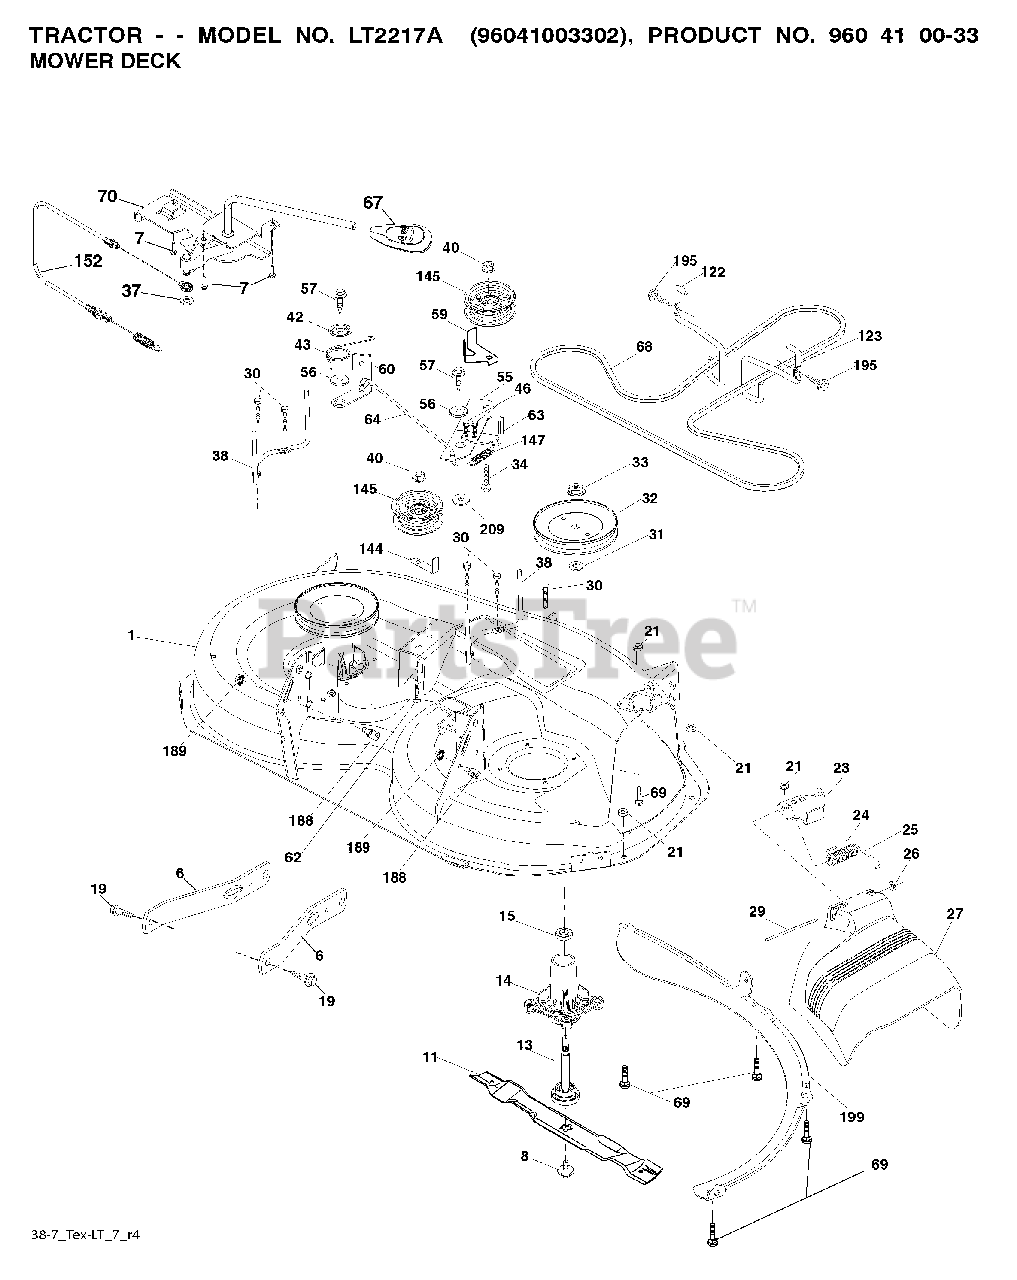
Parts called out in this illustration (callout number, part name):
1	DECK.WELDMENT.42"
6	ARM.SUSPENSION.MOWER.R
7	SCREW
8	BOLT.WASHER.ASM.7/16-2
11	42" HI-LIFT BLADE
13	SHAFT.ASM.MDRL.N/GREASE.38
14	HOUSING MANDREL
16	STRIPPER, MWR ROUND
19	BOLT.SHOULDER
20	BAFFLE.VORTEX
21	LOCKNUT
23	BRKT.DEFLECTOR.38"2005+
24	CAP-SLEEVE LT
25	SPRING.TORSION.DEFLECT
26	NUT PUSH M
27	SHIELD.DEFLECTOR.MOWER.42"BLAC
29	ROD.HINGE
30	SCREW, WASHER HEAD
31	WASHER.SPACER.MANDREL
32	PULLEY.MANDREL.5.438.PD
33	NUT.FLANGE.LOCK.TOP
34	BOLT.3/8-16X1.50
36	PULLEY.IDLER.2006
38	KEEPER.BELT.LH.MANDREL
40	NUT LOCK FLG 3/8-16 UNC
42	SPRING.TORSION.BRAKE
43	SRPING.TORSION.RETAINE
46	SCREW.1/4-20X5/8
47	BRKT.CLUTCH.CABLE
55	IDLER.ARM
56	SPACER.RETAINER
57	SCREW 3/8-16X1
59	GUARD, BELT
60	ARM BRAKE MOWER
62	BOLT
63	ARM BRAKE MOWER
64	LINK BRAKE
67	HANDLE.CLUTCH.CABLE.LT
68	BELT.DRIVE.MOWER.TEX.42"
69	BOLT
70	CLUTCH.ASM.MANUAL.LT.TEX
113	BOLT.5/16HEX.WHS.HD
117	WHEEL.GAGE.HALF.SPOKED
118	LOCKNUT
119	WASHER
122	KEEPER BELT ENGINE LH
123	KEEPER BELT RH
144	KEEPER.BELT.MOWER
145	PULLEY.IDLER.48"PRIMARY
147	RETURN SPRING
152	CLUTCH CABLE
188	STUD.FASTNER.W/ANTI-ROTATE
189	NUT LOCK HEX FLANGE 5/16-18
192	BRKT.BRAKE.STAND.LH.
195	SCREW, 3/8-16X3/4
